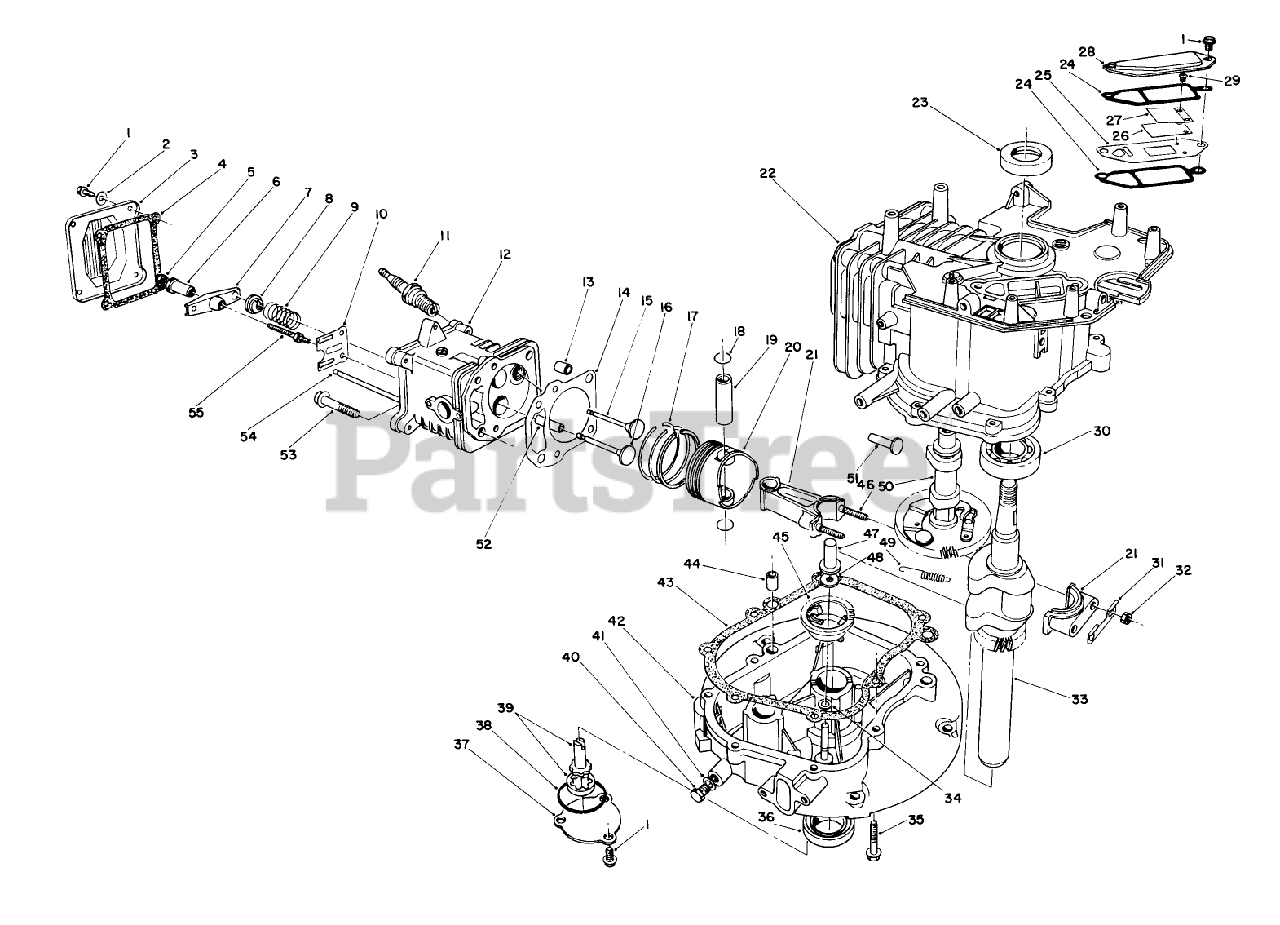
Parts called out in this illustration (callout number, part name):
2	WASHER
3	COVER
6	PIVOT
8	RETAINER
10	GUIDE
11	SPARK PLUG
12	CYLINDER HEAD
14	GASKET
16	VALVE-INTAKE
17	RING SET
22	ENGINE BLOCK
25	Plate-Breather
26	Valve-Reed
27	Retainer-Reed Valve
29	Screw-Reed Valve
30	BEARING
33	CRANKSHAFT
37	COVER
38	O-RING
40	OIL DRAIN PLUG
41	GASKET
43	GASKET
47	PLUNGER
48	WASHER
50	CAMSHAFT
51	TAPPET
52	GUIDE
